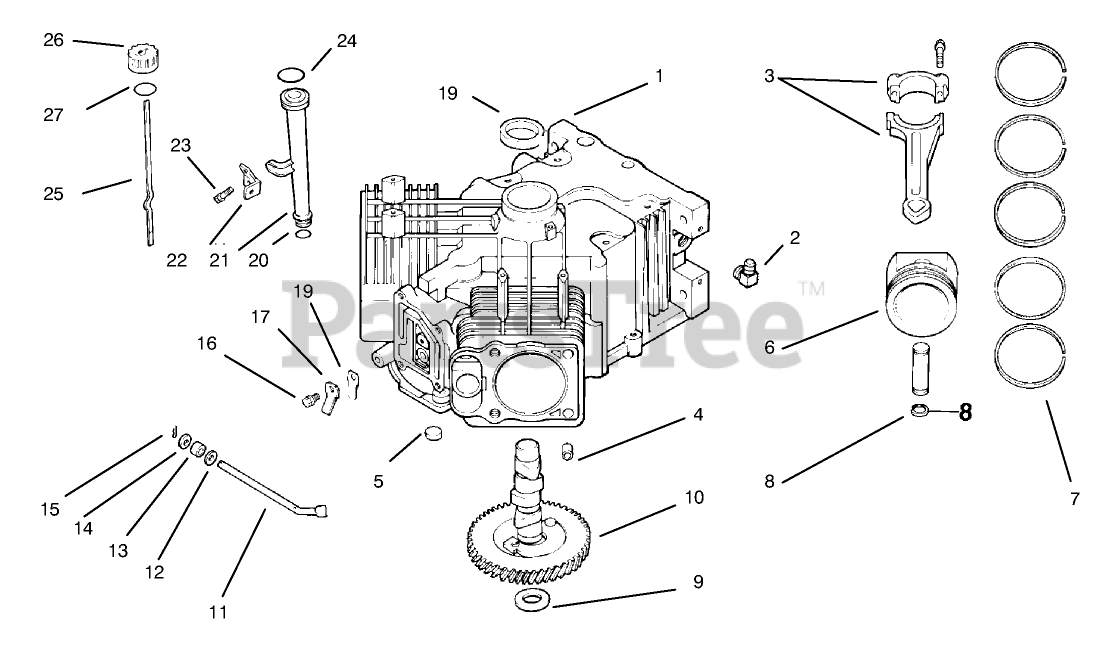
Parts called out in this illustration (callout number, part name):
1	Miniblock
2	Fitting
3	Connecting Rod STD
3	Connecting Rod .25
4	Pin-Dowel
5	Plug
6	Piston ASM STD INC4/7/8
6	Set-Piston w/Ring .25
6	Piston ASM .50 INC4/7/8
7	Ring Set(Std.)
7	Set-Ring .25
7	Set-Ring .50
8	Retainer-Piston Pin
9	Shim-Camshaft
10	Camshaft
11	Shaft-Governor Cross
12	Washer
13	Seal-Cross Shaft
14	Washer
15	Pin-Hitch
16	Screw
17	Retainer-Reed
18	Beed-Breather
19	Seal-Oil
20	"O"Ring
21	Tube-Oil Fill
22	Bracket-Oil Tube
23	Screw
24	"O"Ring
25	Dipstick INC 26-27
26	Kit-Oil Fill Cap
27	"O"Ring
